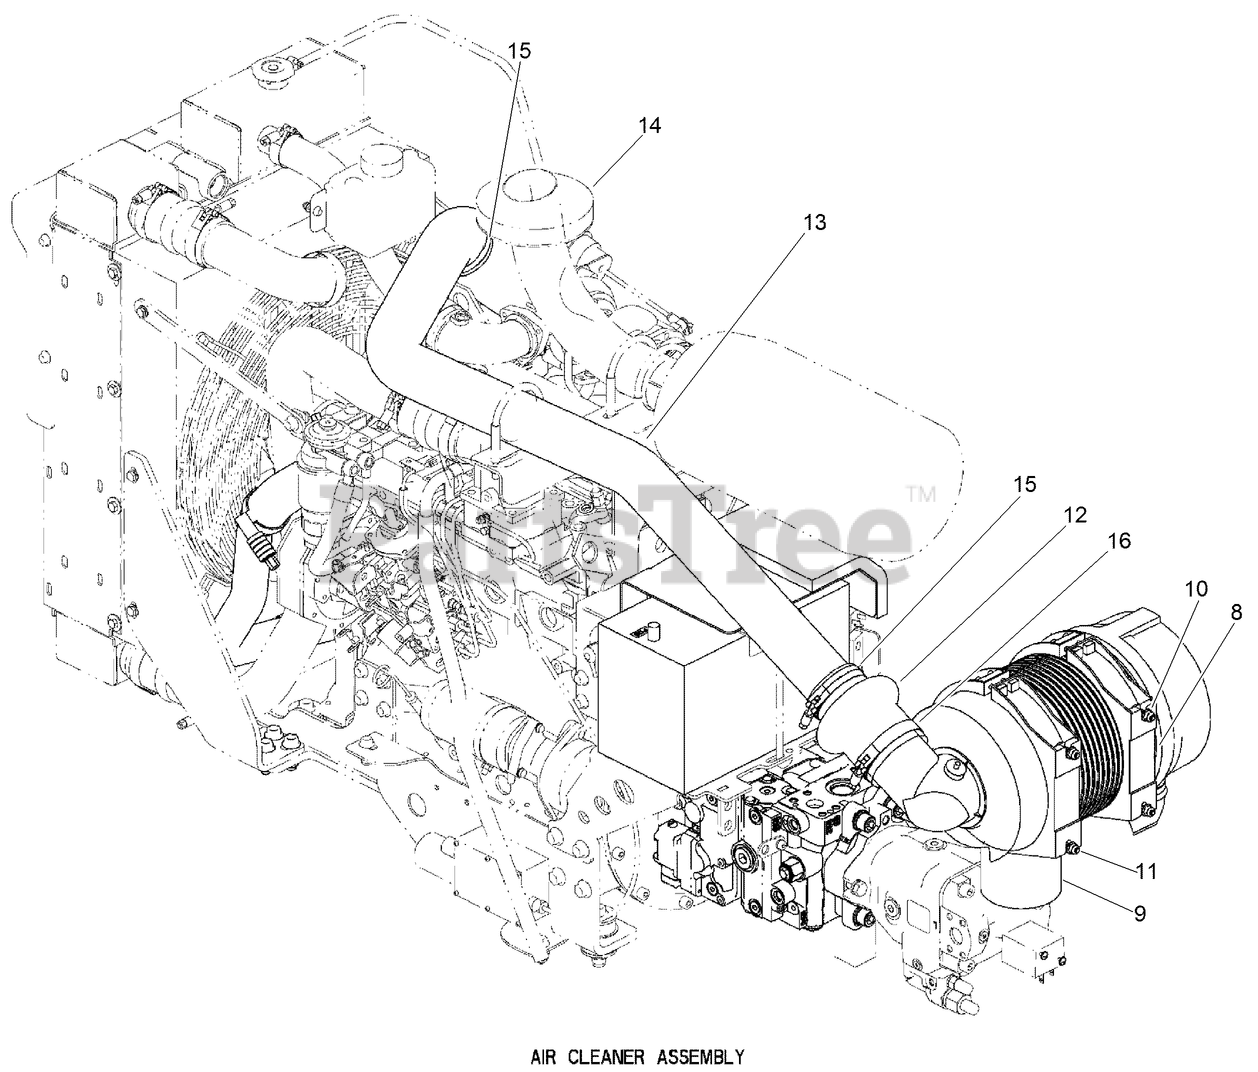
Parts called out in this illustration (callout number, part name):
8	MOUNT-Air Cleaner
9	ASM-Air Cleaner
10	SCREW-HHF
11	NUT-TORQUE, PREVAILING
12	REDUCER-HOSE
13	TUBE - Air Intake
14	ELBOW - 90 Deg Intake 3.00 x 90
15	CLAMP - TBolt, Spring Load Min 3.38 Max 3.69
